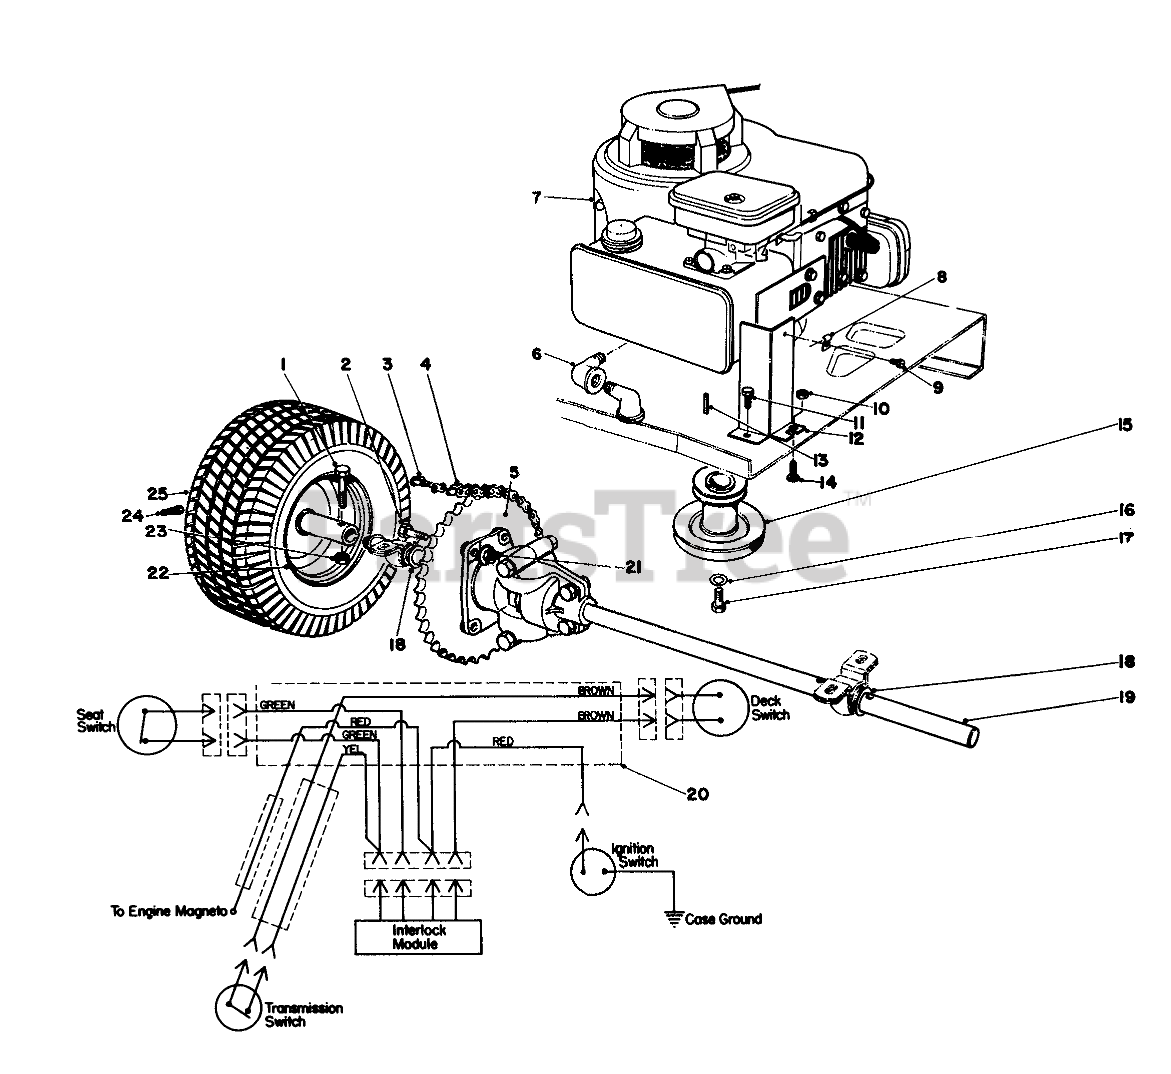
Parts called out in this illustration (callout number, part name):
1	SCREW-HH
2	SCREW-HH
3	LINK-CONNECTING
4	ROLLER CHAIN
5	Sprocket
6	Street Elbow
7	Engine
9	Screw
10	NUT-KEPS
11	SCREW-HWHTF
12	Support-Wire
14	5/16-18X5/8 TRS HD MS
15	ENGINE SHEAVE
16	WASHER-LOCK
17	SCREW-HH
18	WASHER
19	Differential
20	Wiring Harness
21	NUT-LOCK, CONE
23	NUT-LOCK, CONE
24	STEM-VALVE
25	Tire
